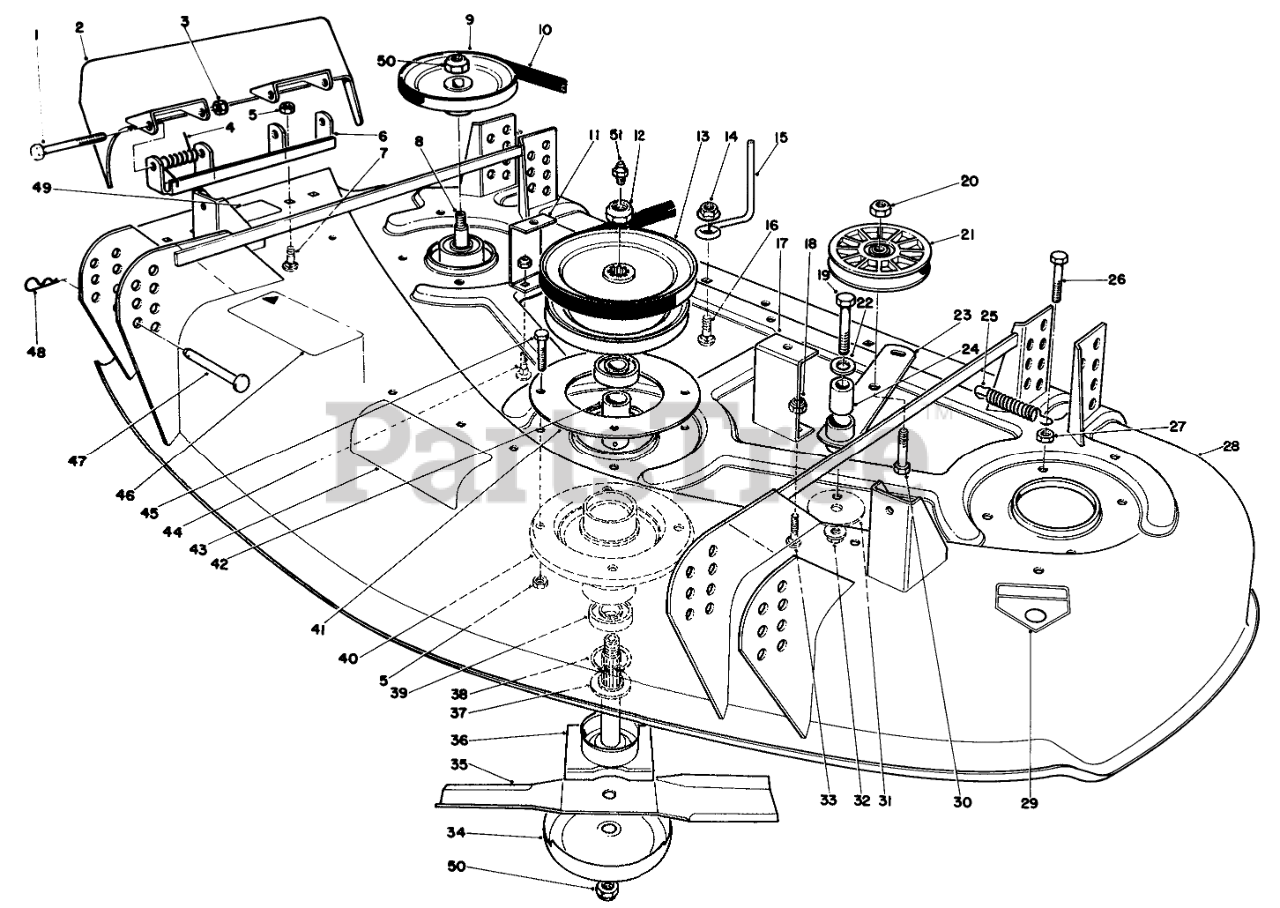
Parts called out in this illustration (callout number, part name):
1	SCREW-HH
2	GRASS DEFLECTOR WA R
3	NUT-HEX
4	SPRING
5	NUT-LOCK, CONE
6	PIVOT BRKT WA R/B
7	SCREW-CARR
8	SPDL/BLD RET.WA
9	DECK PULLEY
10	V-BELT
11	Bracket-Cover RH
12	NUT-LOCK, NI
13	PULLEY WA
14	NUT-HF
15	ROD-BELT
16	BOLT-CARR
17	Bracket-Cover
18	NUT-LOCK, NI
19	SCREW-HH
20	NUT-HEX
21	Pulley
22	WASHER-FLAT
23	Idler Arm
24	SLEEVE
25	Spring-Extension
26	SCREW-HH
27	NUT-JAM
28	Housing
29	DECAL-DANGER
30	SCREW-HH
31	WASHER-END
32	NUT-HF
33	SCREW-CARR
34	Cup
35	Blade
36	SPDL/BLD RET.WA
37	Spacer-Bearing
38	RING-RETAINING
39	BEARING-BALL
40	Spindle Tube
41	DECK RING
42	BEARING SPACER
43	DECAL
44	BOLT-CARR
45	SCREW-HH
46	CAUTION DECAL
47	PIN-CLEVIS
48	PIN-HAIR
49	DECAL-CAUTION, BLADE
50	NUT-LOCK NI
51	FITTING-GREASE
